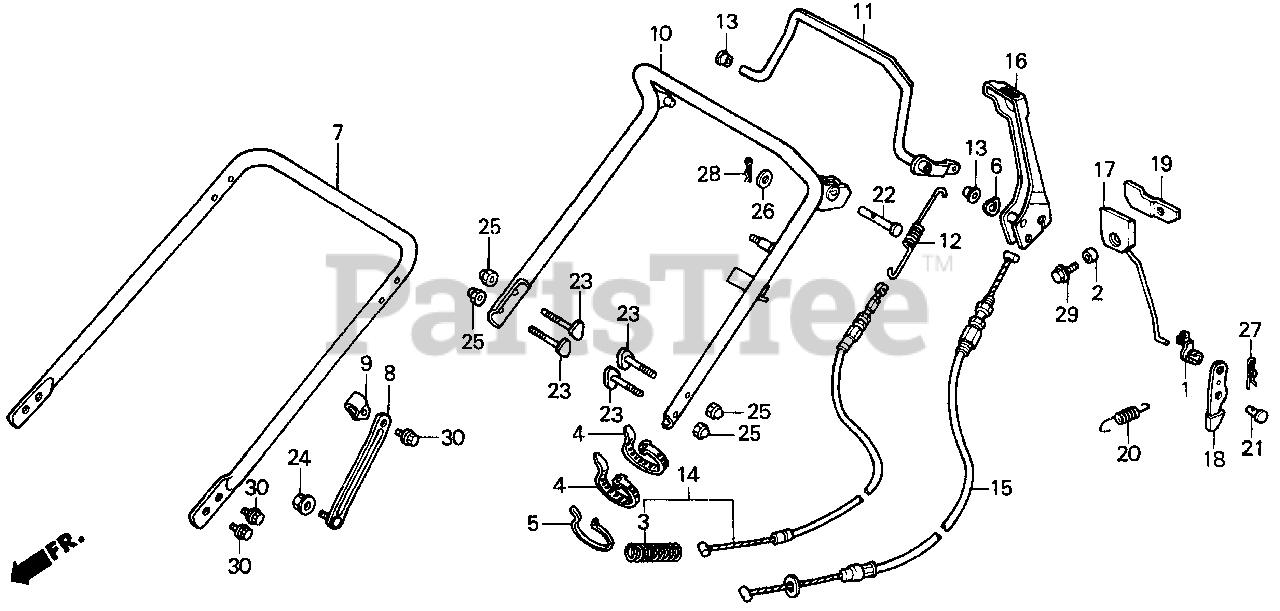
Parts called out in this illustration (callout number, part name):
1	JOINT, ROD
2	COLLAR, FAN
3	SPRING, CLUTCH RETURN
4	TIE, CABLE
5	TIE, CABLE (NATURAL 2.4X92) Use up to Frame SN 1300359.
6	WASHER, EQUALIZER (NOT AVAILABLE)
7	PIPE, HANDLE (LOWER)
7	PIPE, HANDLE (LOWER) *NH190M* (VINTAGE GRAY METALLIC)
7	PIPE, HANDLE (LOWER) *NH105* (MAT BLACK)
8	PLATE, HANDLE SUPPORT
9	HANGER, HANDLE SUPPORT
10	PIPE, HANDLE (UPPER)
11	LEVER, CLUTCH (NOT AVAILABLE)
12	SPRING, CLUTCH
13	BUSH, CLUTCH LEVER
14	CABLE, SELF
15	CABLE, ROTO-STOP
16	LEVER, ROTO-STOP (NOT AVAILABLE)
17	ROD, RATCHET PUSH (NOT AVAILABLE)
18	LEVER, LOCK (NOT AVAILABLE)
19	PLATE, PUSH ROD (NOT AVAILABLE)
20	SPRING, RATCHET RETURN
21	PIN, SEAT HINGE
22	PIN, CLUTCH LEVER
23	BOLT, HANDLE HOLDER (8X36)
24	NUT, FLANGE (8MM)
25	NUT, CAP (8MM)
26	WASHER, PLAIN (8MM)
27	PIN, LOCK (6MM)
28	PIN, LOCK (8MM)
29	BOLT, FLANGE (8X14)
29	BOLT, FLANGE (8X16) Use from Engine SN 1000016.
30	BOLT, FLANGE (6X10)
